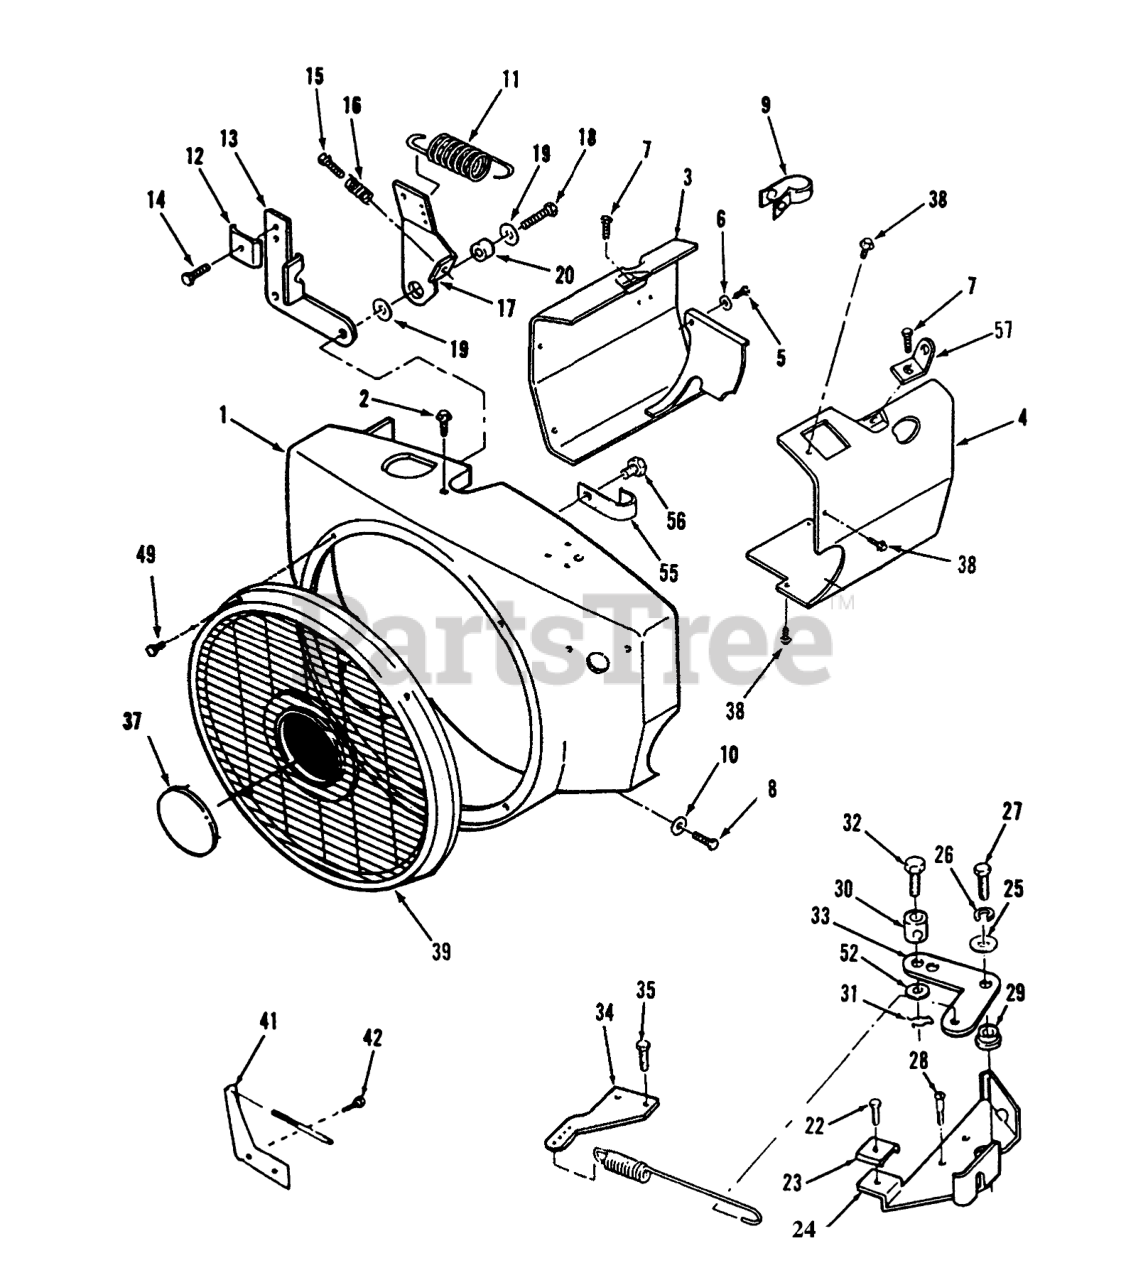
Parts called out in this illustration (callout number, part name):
1	BLOWER-HOUSING
2	HEX HD CAPSCREW
3	CYLINDER AIR HSG L H
4	Housing, Cylinder Air-RH
5	SCREW-HH
6	WASHER-FLAT
7	SCREW-HWH
8	SCREW-HH
9	Clamp
10	WASHER-FLAT
11	SPRING
13	Bracket-Cable
14	SCREW-TAPPING
15	SCREW-TAP
16	SPRING
17	Arm, Governor Control Without Swivel-Zinc Plated
19	WASHER-FLAT
20	BUSHING
22	SCREW-HWH
24	BRKT-GOVERNOR CONTRL
25	WASHER-FLAT
26	Washer-Lock
27	Bolt
28	HEX HD CAP SCREW
29	BUSHING-GOV CONTROL
30	BUSHING
31	PIN-COTTER
32	Bolt
33	LINK-GOV CONTROL
34	ADAPTER-GOV ARM
35	SCREW-TAPPING PAN HD
37	NAME-PLATE TORO LOGO
38	SCREW-HWH
39	GUARD-STATIONARY
41	BRACKET
42	SCREW-HWH
48	SCREW - THREAD CUTTING
49	SCREW-PAN HEAD
55	CLIP-WIRE
56	SCREW-HWH
57	BRACKET-LIFTING
